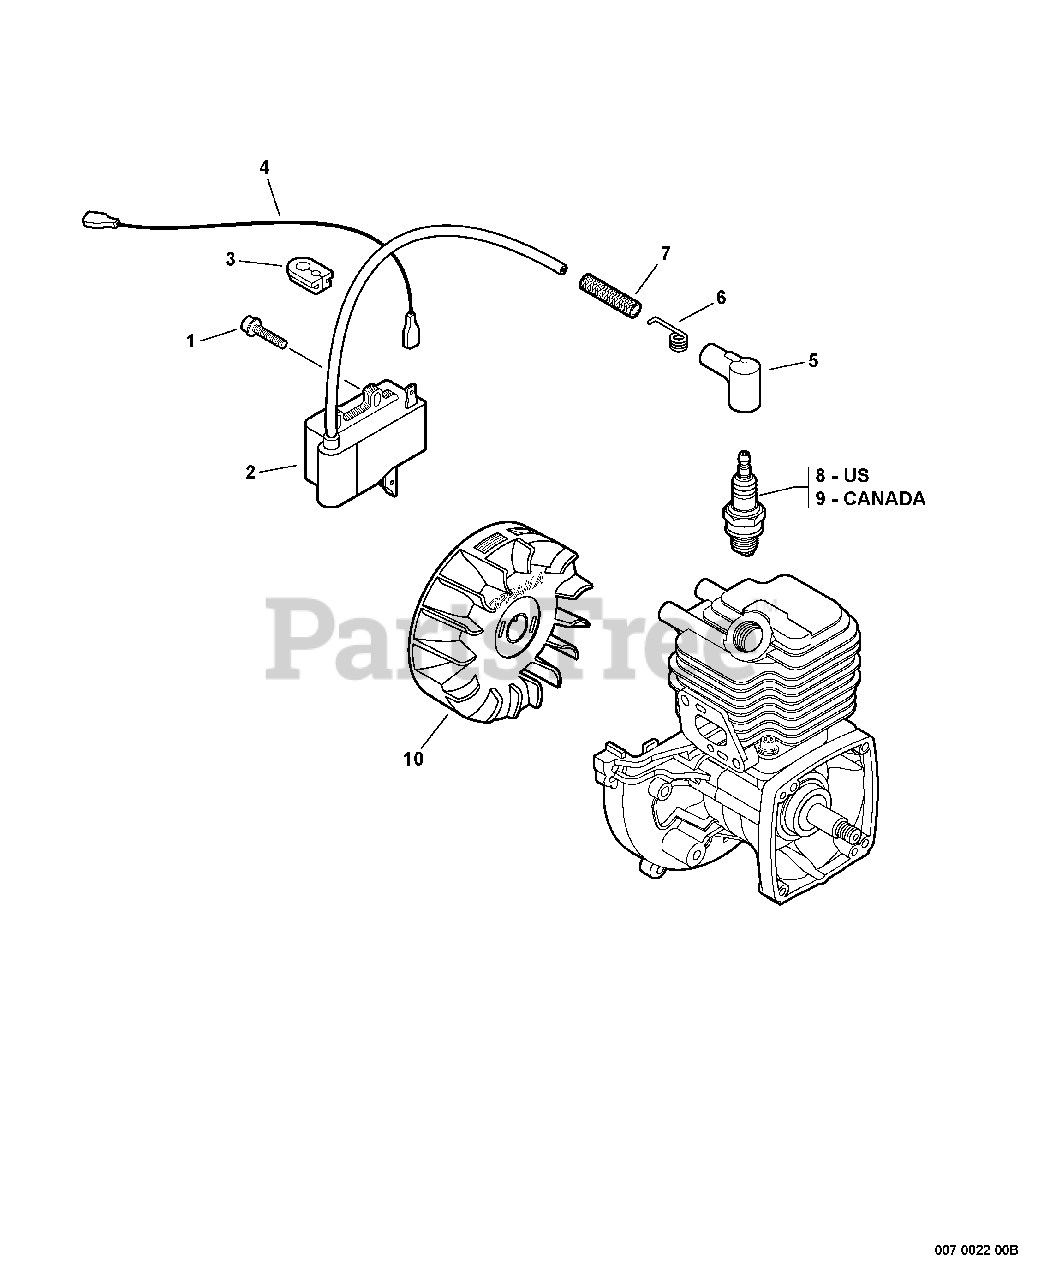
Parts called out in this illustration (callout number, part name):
1	SCREW - 4X20
2	COIL, IGNITION
4	LEAD - IGNITION
5	CAP, SPARK PLUG
6	TERMINAL, SPARK PLUG CAP
7	TUBE, INSULATOR
8	SPARK PLUG -- BPM-8Y
9	SPARK PLUG -- BPMR-8Y
10	FLYWHEEL
